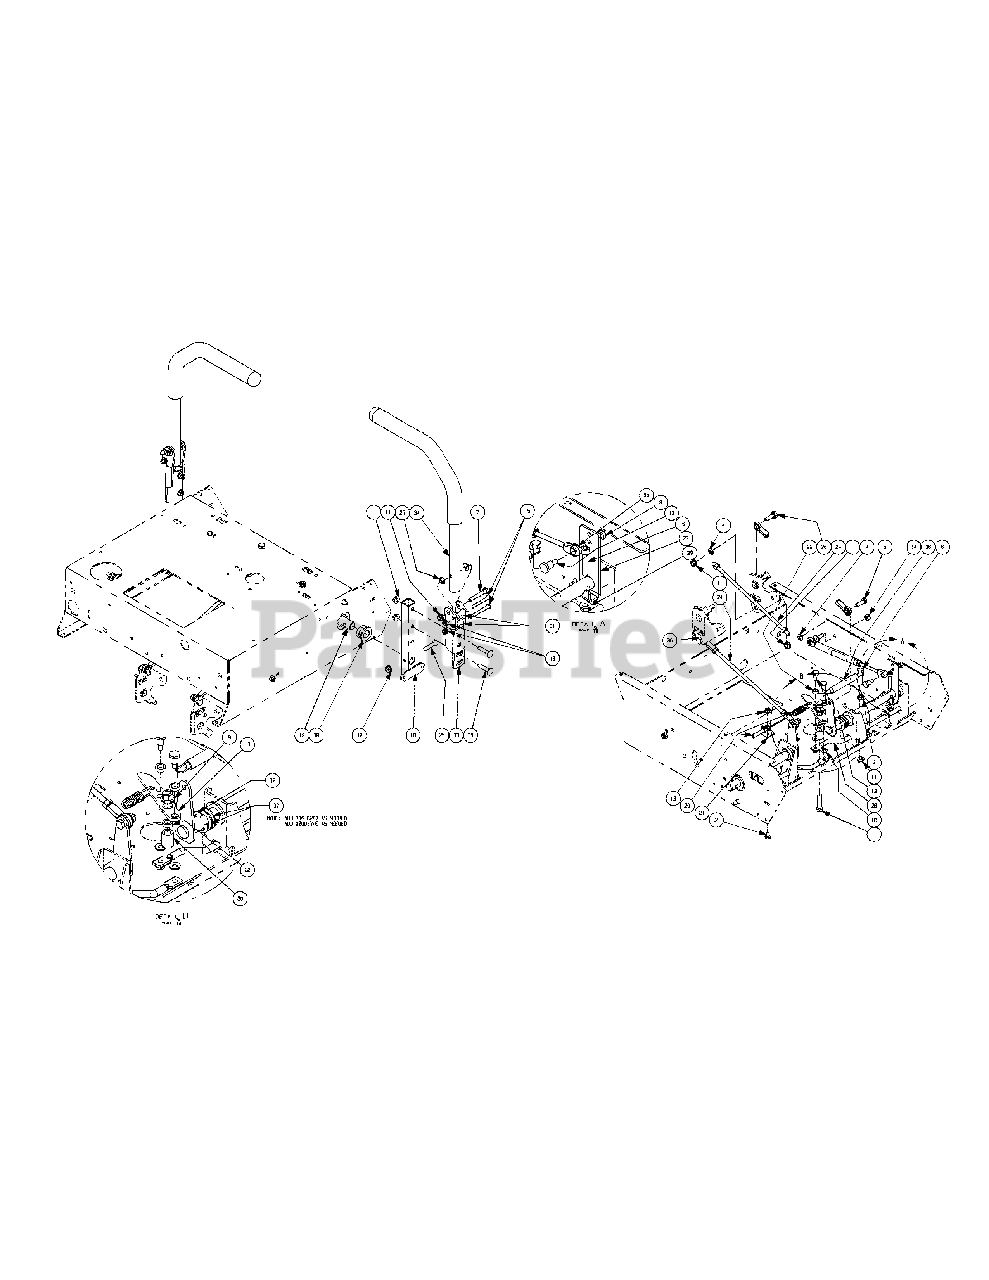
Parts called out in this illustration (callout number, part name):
1	Hex Cap Screw, 3/8-16 x 1-1/2
2	Hex Cap Screw, 1/4-20 x 1/2
3	Hex Nut, 5/16-18
4	Flat Washer, 5/16
5	Hex Head Cap Screw, 5/16-18 x 1.00
6	Hex Cap Screw, 5/16-18 x 1-1/2
7	Hex Cap Screw, 5/16-18 x 2.00
8	Nut, 1/4-28, SS, Nylon Insert
9	Nut, Flange Lock, 3/8-16
10	Flat Washer, 1.4 x .630 x .0515
11	Nut, 5/16-18, Lock
12	Shoulder Screw, 1/4-28
13	Nut, 1/4-20, Hex Flange Lock Nut
14	Nut, Hex, Center Lock, M8
15	Hex Cap Screw, 1/4-20 x 2.00
16	Capscrew, 5/16-18 x 1.50, Socket Head
17	Brake Lever Plate
18	Pivot Bracket Weldment
19	Steering Input Shaft Assembly
20	Spacer, .385 ID x .625 OD x .869
21	Brake Cable Mounting Bracket
22	Spacer, .380 x .563 x .196
23	Damper Mounting Bracket
24	Steering Link Rod
25	Socket Head Capscrew, 5/16-18 x 1.25
26	Shoulder Bolt, .4375 x .1345 x 1.00
27	Bushing, .310 x .172 x .688 x .06
28	Control Lock Rod
29	Control Cable Lock Out
30	Cylinder Return to Neutral
31	Spacer, .25 ID x .38 OD x 1.13
32	Retainer Ring, E-Clip
33	Lapbar Pivot Bracket
34	Lapbar Assembly includes:
34	Control Handle Pivot Tube
34	Grip, 1.0
35	Carriage Bolt, 5/16-18 x 1.50
36	Extension SPring, .53 OD x 4.7
37	Flat Washer, .793 ID x 1.24 OD x .060
38	Hex Flange Bearing, .752 ID
39	Nylock Nut, 5/16-18
